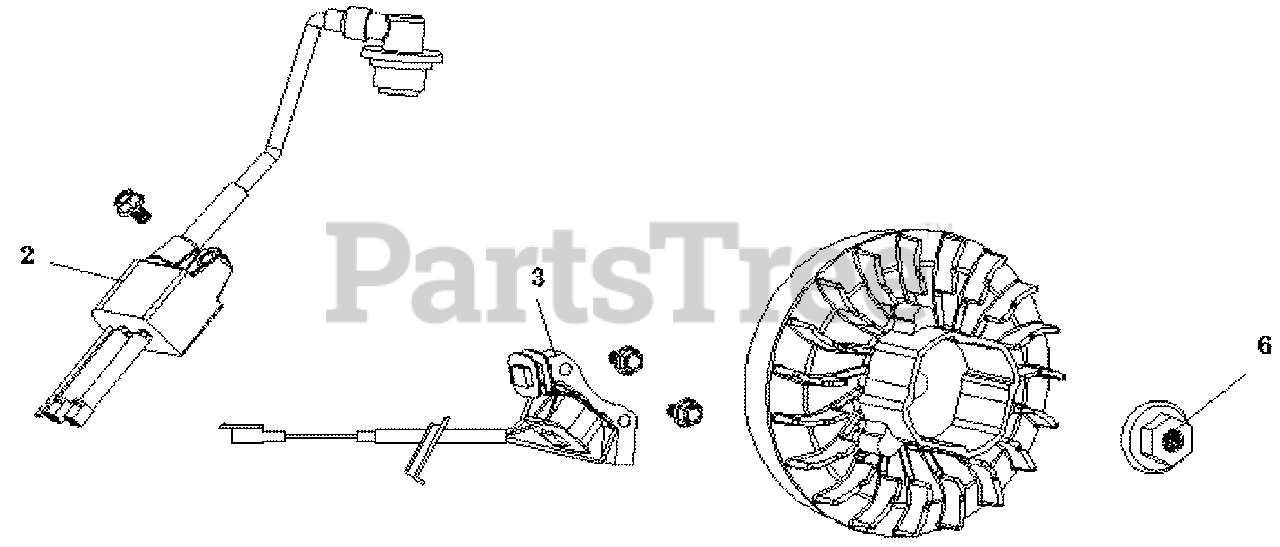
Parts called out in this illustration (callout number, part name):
2	COIL ASSY., IGNITION
3	COIL ASSY., CHARGE
6	NUT FLANGE M12
